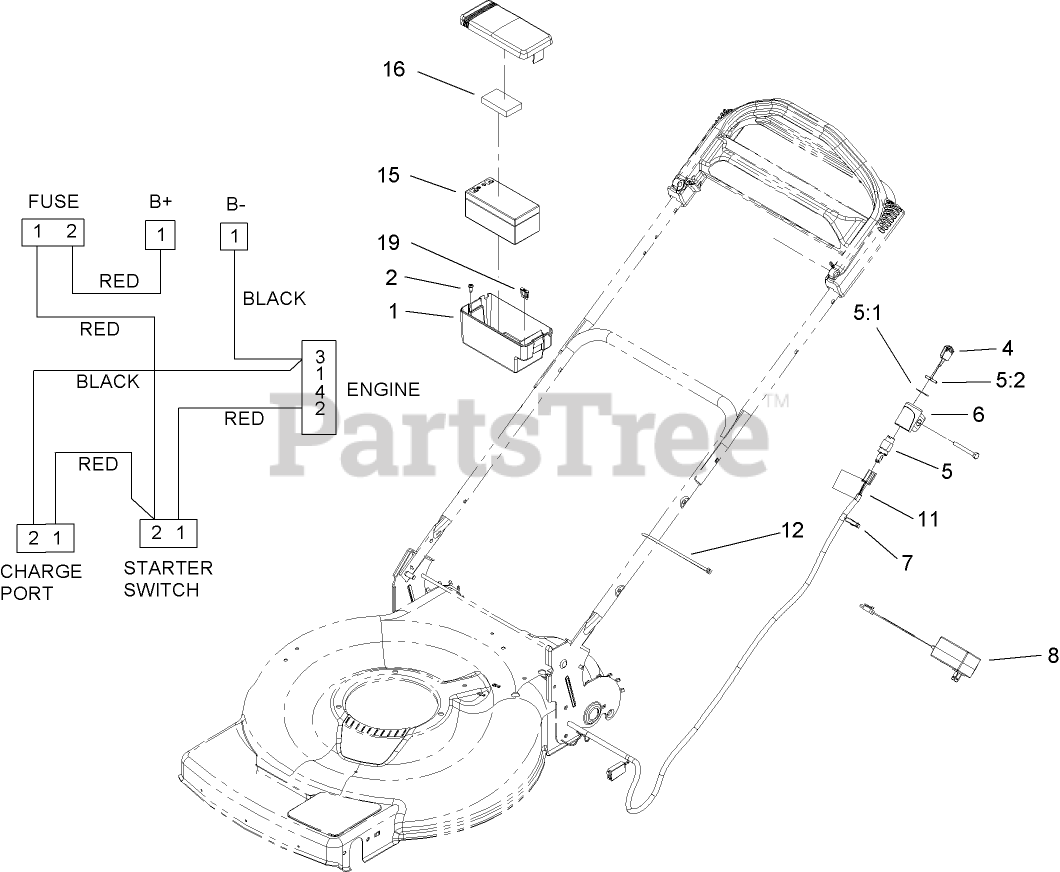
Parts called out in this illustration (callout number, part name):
1	BATTERY BOX ASM
2	SCREW-FORMING, THREAD
5	STARTER SWITCH ASM
5:1	WASHER-LOCK
5:2	NUT-HH
6	MOUNT-SWITCH
7	HARNESS-WIRE
8	CHARGER-BATTERY, 12 VOLT
11	DECAL-WARNING
12	TIE-CABLE
15	BATTERY-WET
16	FOAM-BATTERY, TOP
19	FUSE-40 AMP
